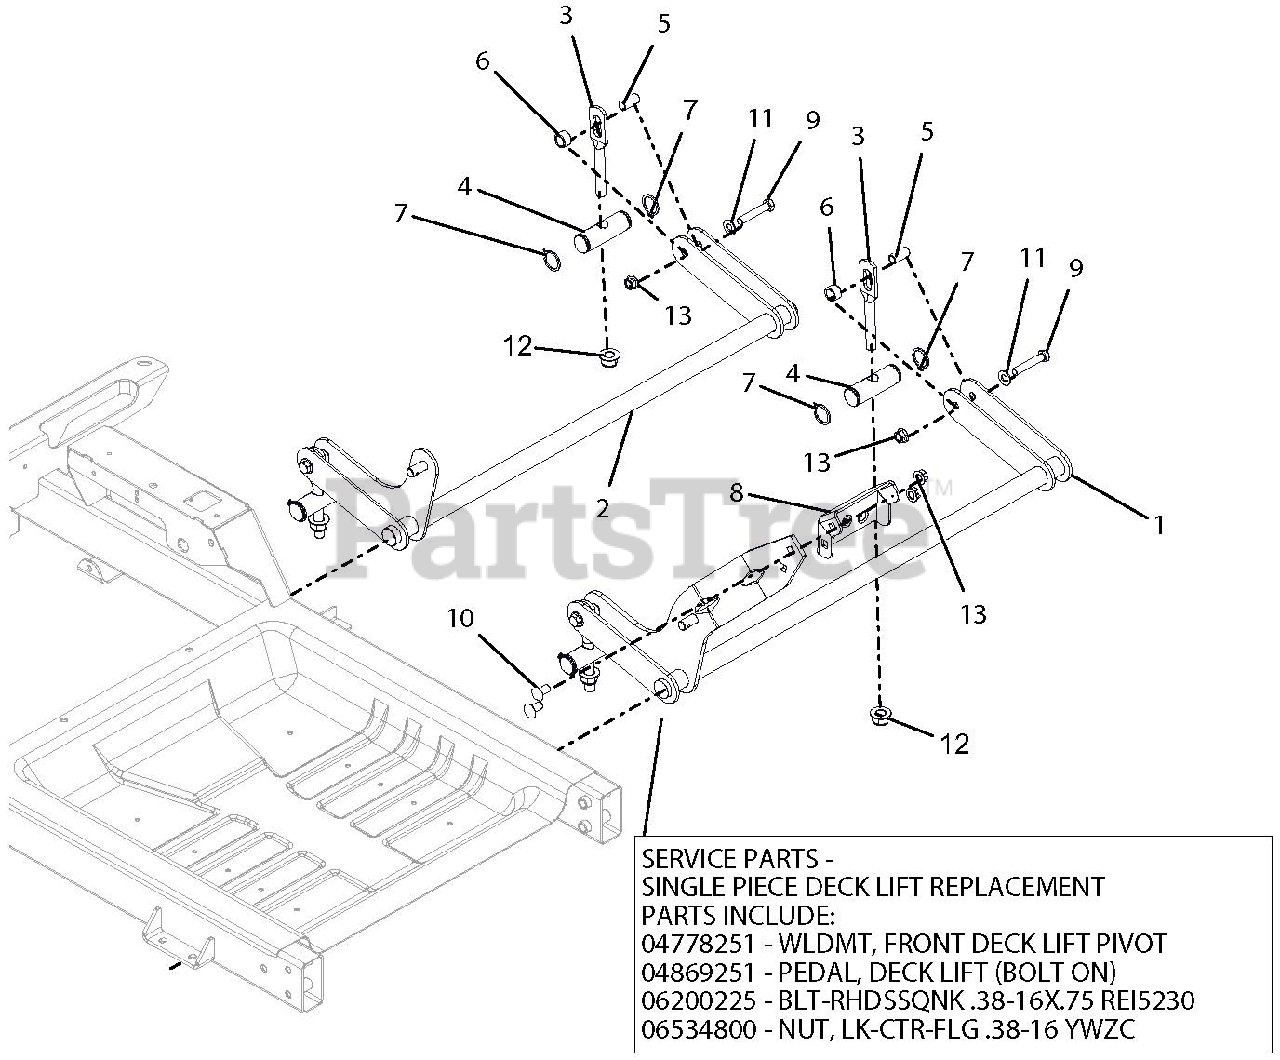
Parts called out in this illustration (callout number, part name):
1	WLDMT, FRONT DECK LIFT PIVOT
2	WLDMT, REAR DECK LIFT PIVOT
3	LINK, DECK
4	SHAFT, DECK LINK PIVOT
5	BSHG, SLV .385 X .500 X 1.045
6	BSHG, SLV .510 X .751 X .475
7	RG-RTNG-EXT 1.00X.078
8	PEDAL, DECK LIFT (BOLT ON)-BLACK
9	BLT-HEX .38-16X2.00 GR8 YWZC
10	BLT-RHDSSQNK .38-16X.75 RIE5230
11	WSHR-FL-STL.406X.812X.065 YWZ
12	NUT-LK-NYL-FLG .50-13 YWZC
13	NUT, LK-CTR-FLG .38-16 YWZC
